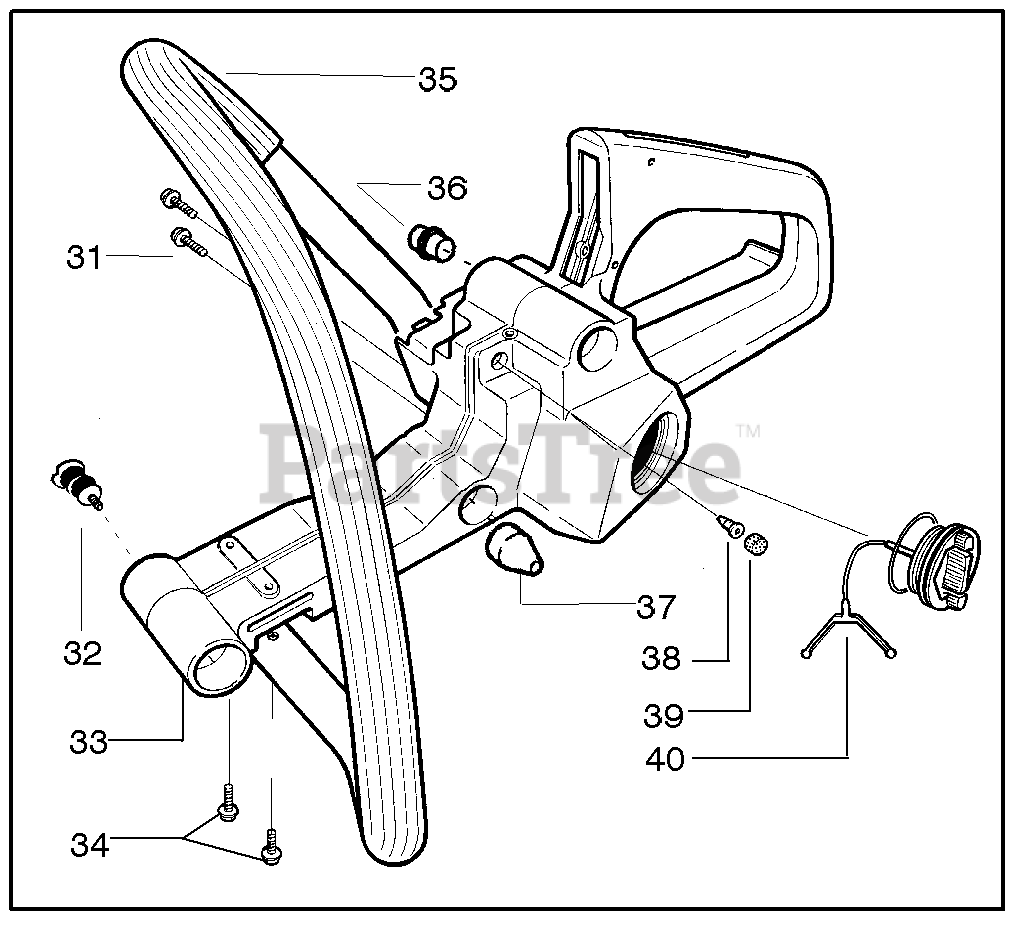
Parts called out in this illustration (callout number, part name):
32	Element - AV Isolator
33	Assy. -Tank/Handle
35	Handle-Front
36	Isolator-Front Handle
38	Valve - Check
39	Plug - Vent
40	Kit-Assy. Fuel Cap
